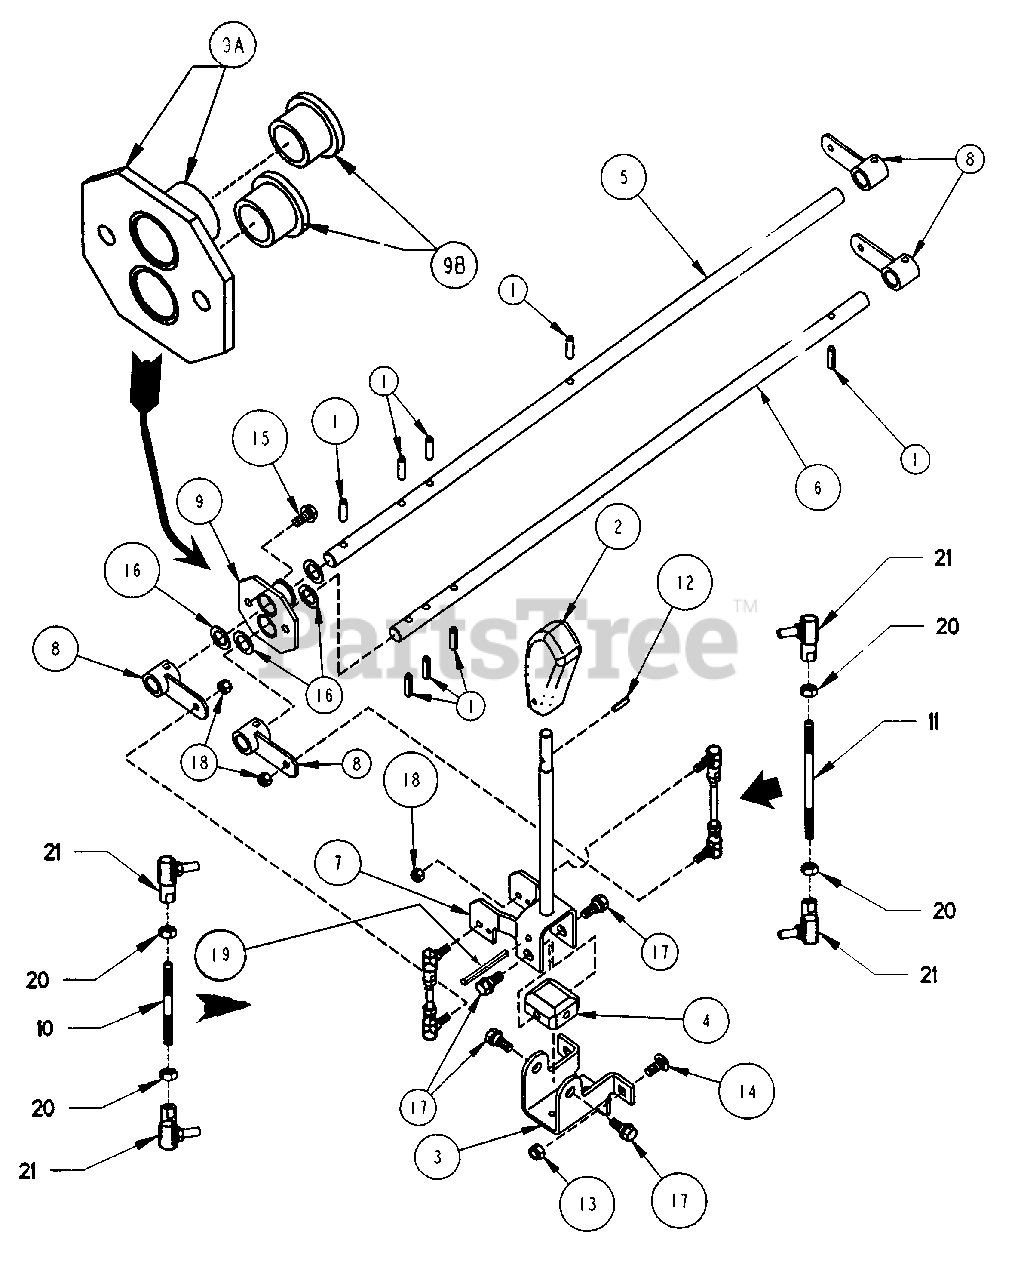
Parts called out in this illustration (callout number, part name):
1	ROLL PIN, 1/4 x 1"
2	HANDLE, Plastic
3	BRACKET, Joystick Mounting
4	BLOCK, Pivot J'Stick Control
5	SHAFT, Upper Cross
6	SHAFT, Lower Cross
7	HANDLE, Joystick Control (Weldment)
8	ARM/HUB Weldment
9	ASSEMBLY, Cross Shaft Support
9A	SUPPORT, Cross Shaft (Weldment)
10	ROD, Threaded 1/4-28 x 2.71 long
11	ROD, Threaded 1/4-28 x 3.85 long
12	ROLL PIN 3/16 x 3/4"
13	NUT, 5/16-18 HEX NYLON LOCK
14	BOLT, 5/16-18 x 3/4" Sq.Nk. Carriage, Grade 5
15	SCREW, 5/16-18 x 5/8" Hex Washer Self-Tap
16	WASHER, 41/64 I.D. x 1" O.D. Flat
17	BOLT, 5/16-18 Shoulder
18	NUT, 1/4-28 Hex Nyloc
19	ROLL PIN, 1/4 x 2-3/4"
20	HN, 1/4F GR5 YZ
21	BALL-JOINT
